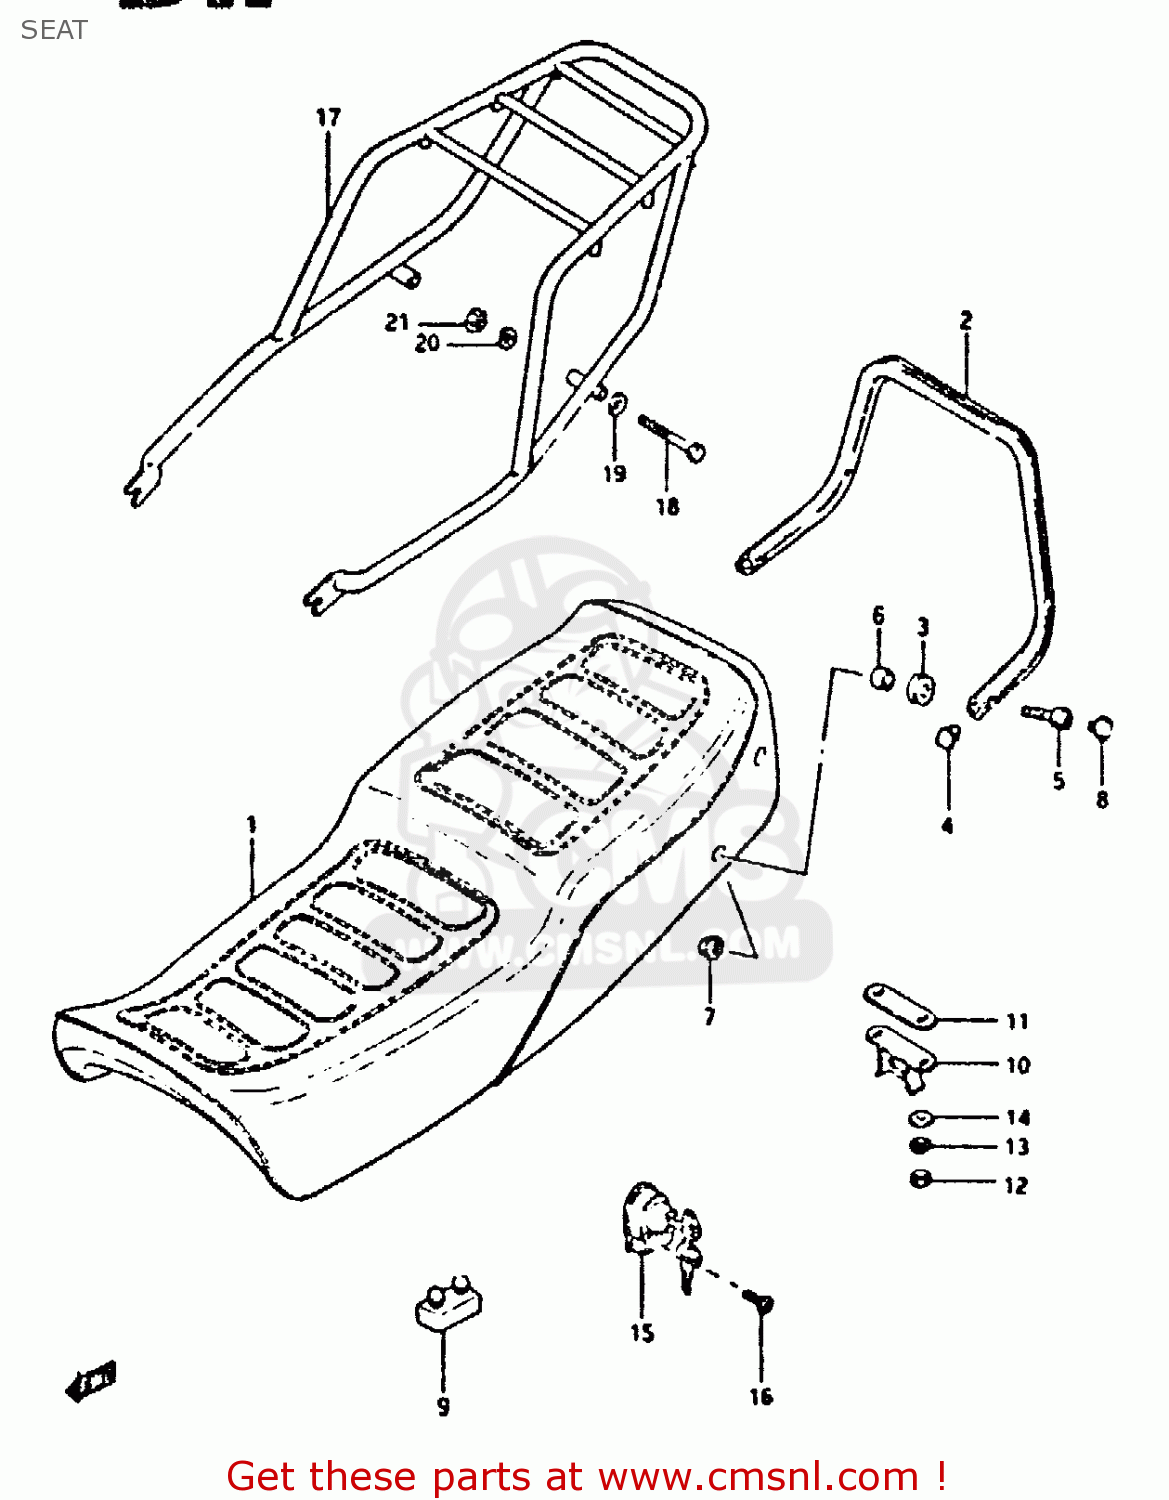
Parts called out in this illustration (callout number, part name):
1	SEAT (BLACK)
2	HANDLE,PILLION RIDER
3	CUSHION
4	END,PILLION RIDER HAND
5	BOLT
6	SPACER,REAR
7	NUT
8	CAP(OD:14.5)
9	CUSHION
10	STRIKER,SEAT LOCK
11	SHIM,SEAT LOCK STRIKER
12	NUT 6MM
13	LOCK WASHER
14	WASHER
15	LOCK ASSY,HELMET
16	BOLT 5X25
17	CARRIER, SPORTS
18	BOLT
19	WASHER
20	LOCK WASHER
21	NUT
